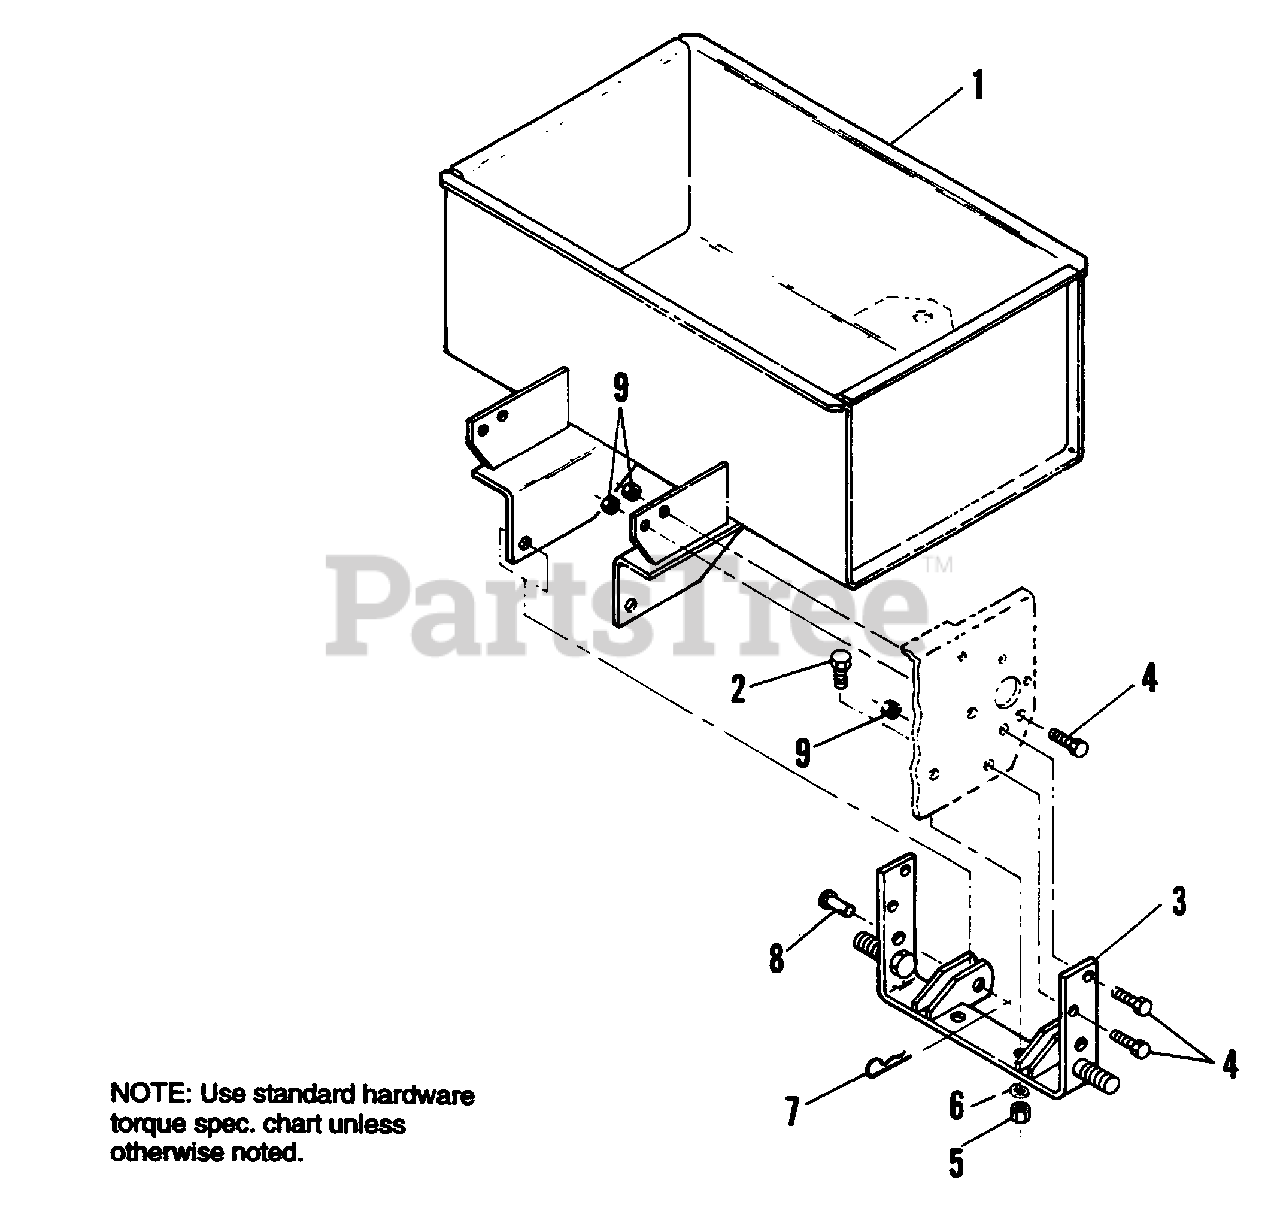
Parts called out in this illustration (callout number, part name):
1	BOX, Ballast
2	CAPSCREW, Hex Hd., 1/2-13 x 1-1/4
3	BRACKET ASSY., Hitch
4	CAPSCREW, Hex Hd., 7/16-14 x 1-1/4
5	NUT, Hex, 1/2-13
6	LOCKWASHER, 1/2
7	PIN, Hair Cotter, 5/32 x 11/16
8	PIN, Clevis, 1/2 x 1-15/16
9	LOCKNUT 7/16-14
